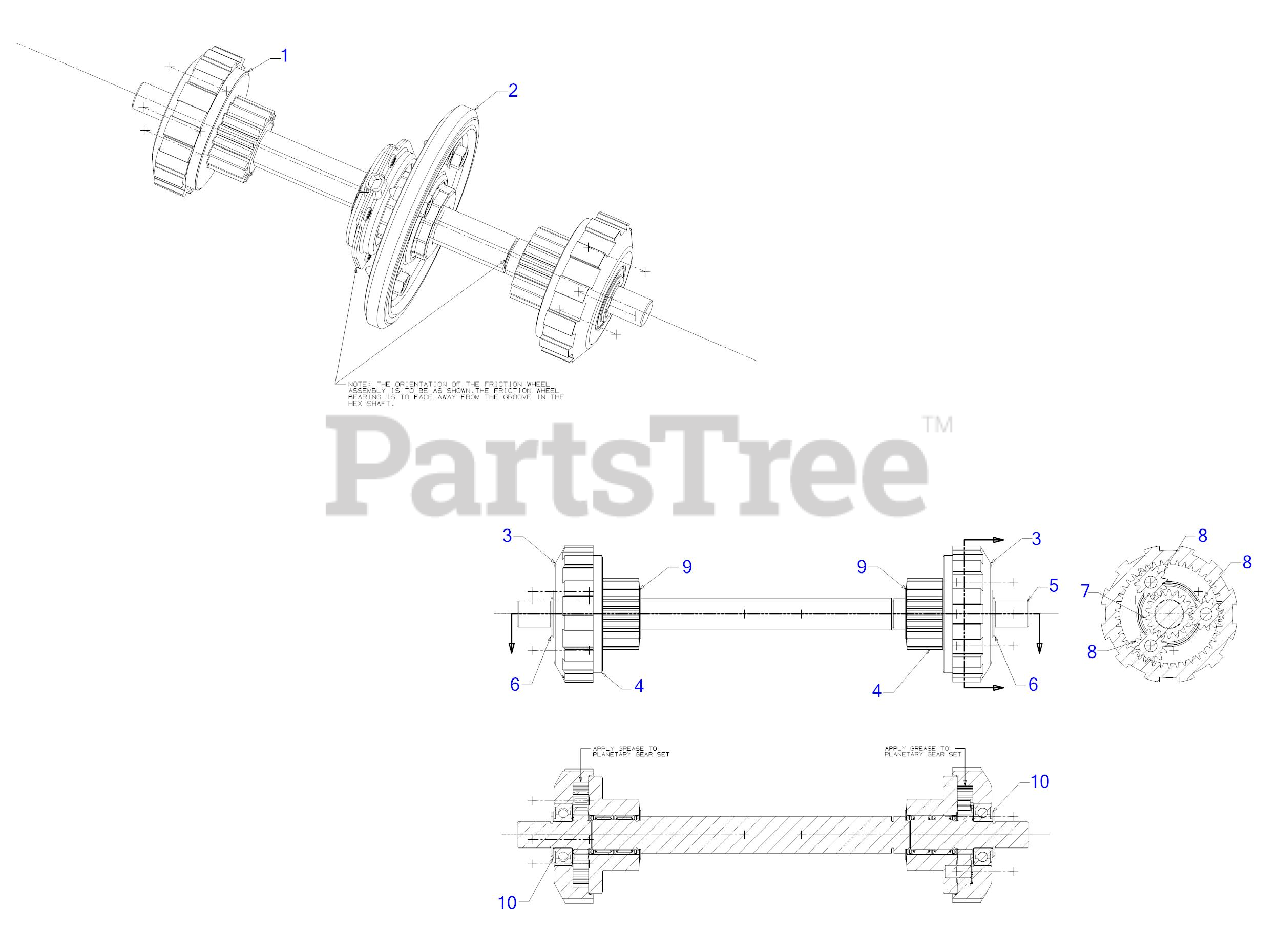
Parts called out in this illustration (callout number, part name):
1	PLANETARY SHAFT ASSEMBLY
2	FRICTION WHEEL ASSEMBLY
3	PLANETARY RING GEAR ASSEMBLY
4	CARRIER ASSEMBLY
5	HEX SHAFT
6	E-RING
7	SUN GEAR 18T
9	THRUST WASHER .75X 1.25X .031
10	FLAT WASHER .67X 1.174X .02
